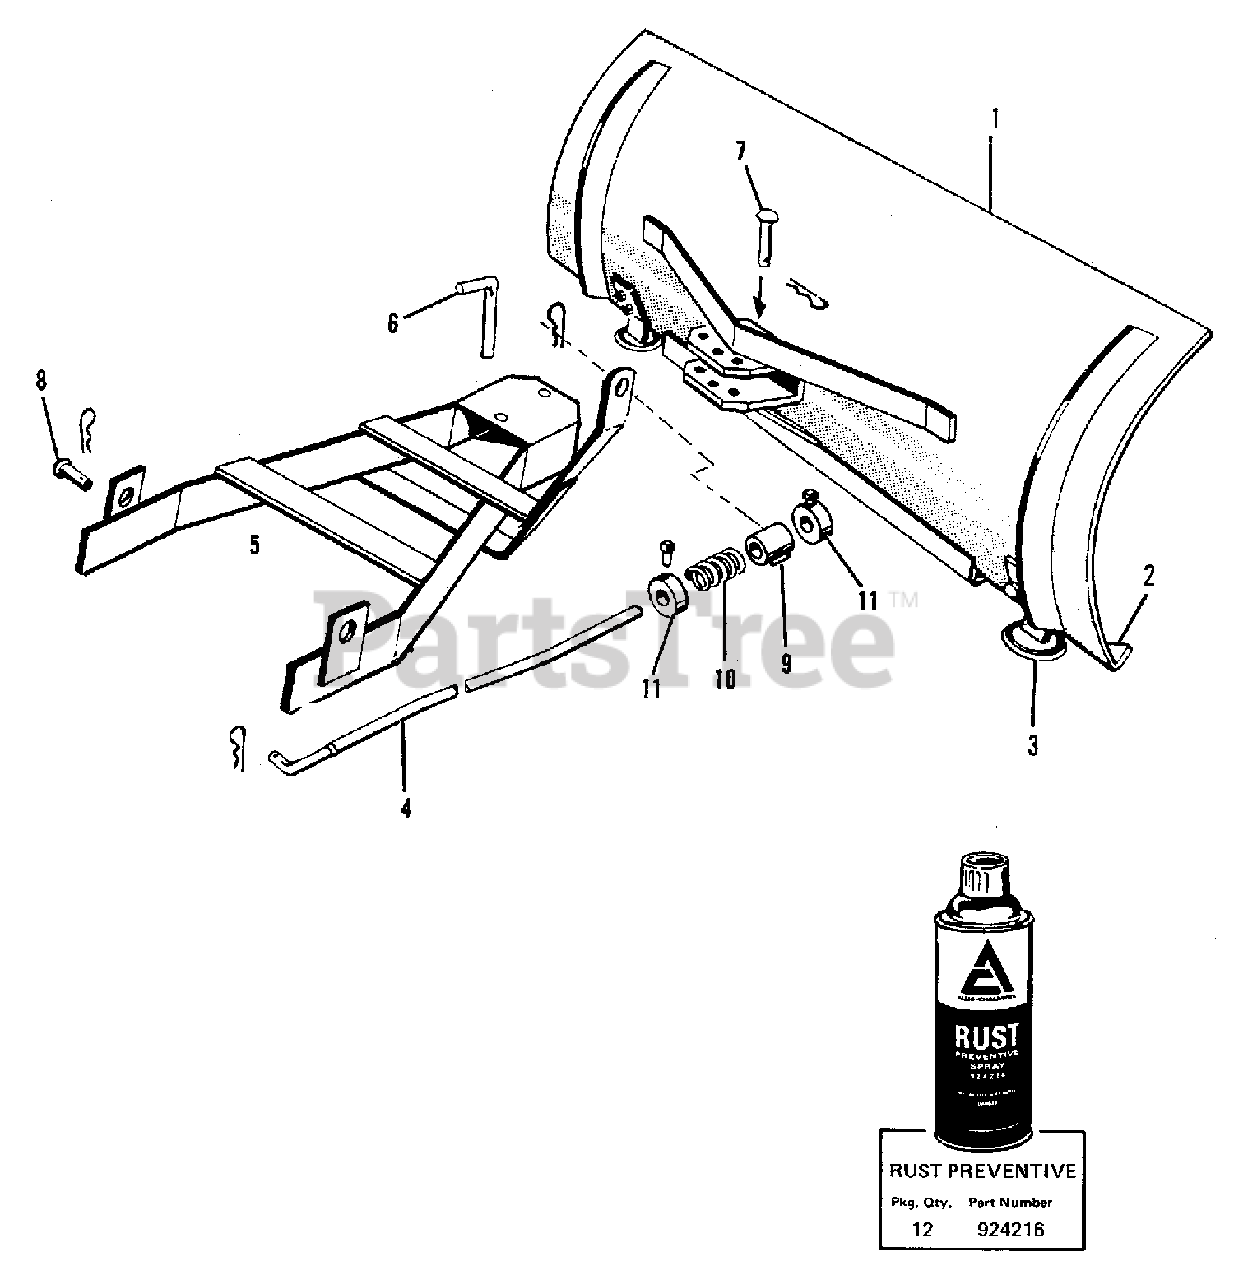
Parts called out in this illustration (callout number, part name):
1	BLADE ASSEMBLY, 42"
2	PLATE, Wear
2	BOLT, 3/8NC x 3/4
2	LOCKWASHER, 3/8
2	NUT, 3/8NC
3	SHOE ASSEMBLY, Blade
3	BOLT, 3/8NC x 1
3	LOCKWASHER, 3/8
3	NUT, 3/8NC
4	PIN, Quick
5	FRAME ASSEMBLY, Push Bar
6	PIN, Pivot
7	PIN, King
7	PIN, Quick
8	PIN, Hitch
8	PIN, Quick
9	GUIDE ASSEMBLY, Rod
11	COLLAR, Set
11	SETSCREW, 5/16NC x 1/2, GR8 (Square Head Cup Point)
11	WASHER, 17/32 x 1-1/4 x 16 Ga.
